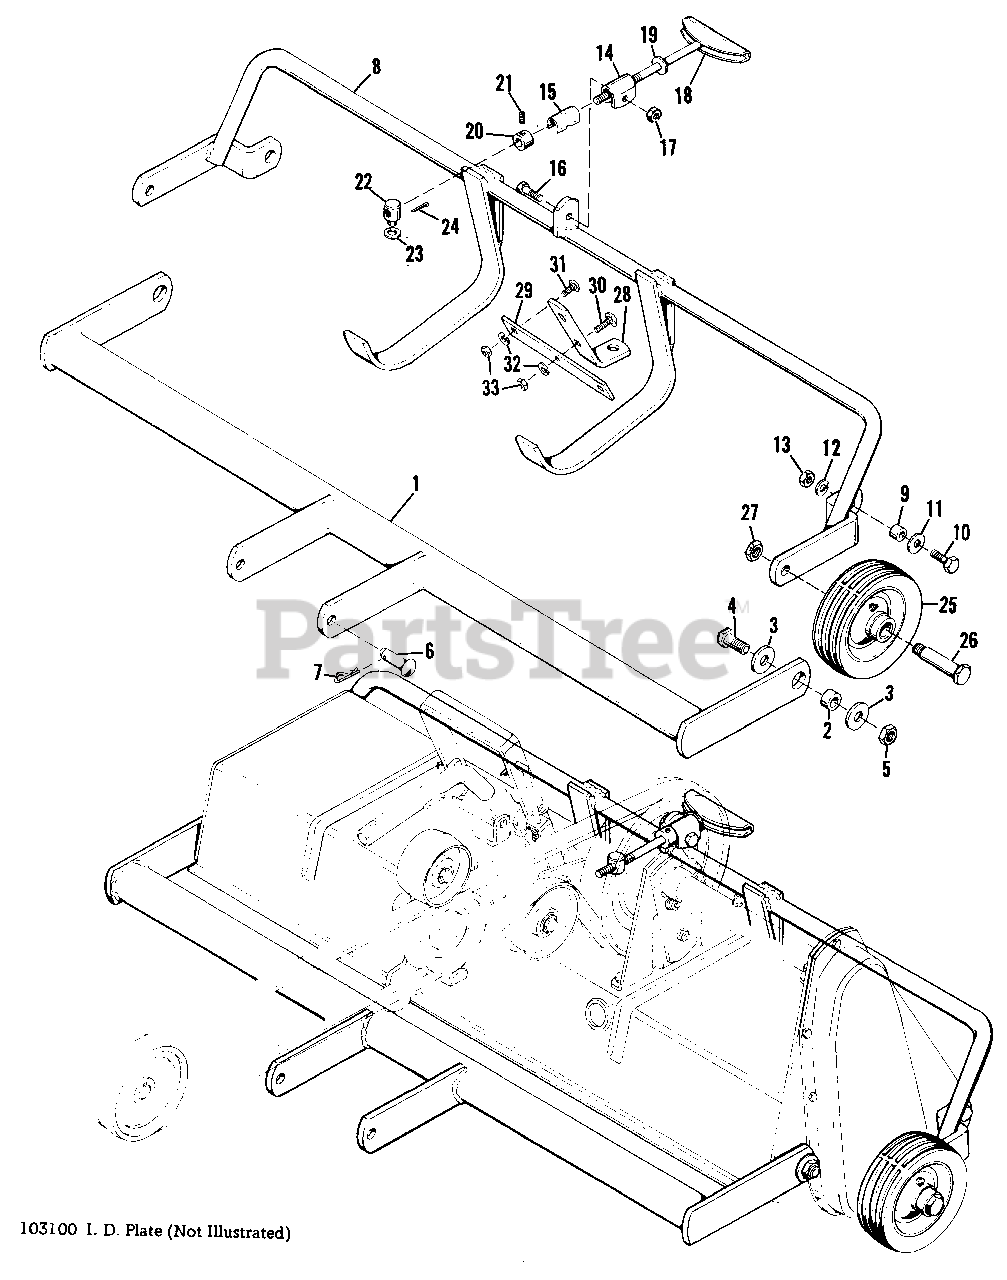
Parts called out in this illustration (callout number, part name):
1	Hitch Assembly
3	Plain Washer, 1/2"
4	Hex Capscrew, 1/2"-13 x 1-1/4" lg.
5	Hex Nut, Full Lock, 1/2"-13
7	Spring Clip
8	Adjuster Assembly
10	Hex Capscrew 3/8"-16 x 1-1/4" lg.
11	Plain Washer, 3/8"
12	Lock Washers, 3/8"
13	Hex Nut, Full, 3/8"-16
15	Guide Liner
16	Hex Capscrew, 5/16"-18 x 1-1/4" lg.
17	Hex Nut, Full Lock, 5/16"-18
18	Adjusting Screw Assembly
19	Plain Washer, 3/8"
20	Set Collar
21	Set Screw, 1/4"-20 x 5/16" lg.
23	Plain Washer, 5/16"
24	Cotter Pin, 3/32" x 3/4" lg.
25	Wheel & Tire Assembly
26	Wheel Bolt
27	Hex Nut, Full, Lock, 7/16"-14
29	Tow Bar Reinforcer
30	Carriage Bolt, 5/16"-18 x 1" lg.
31	Carriage Bolt, 5/16"-18 x 3/4" lg.
32	Lock Washer, 5/16"
33	Hex Nut, Full, 5/16"-18
